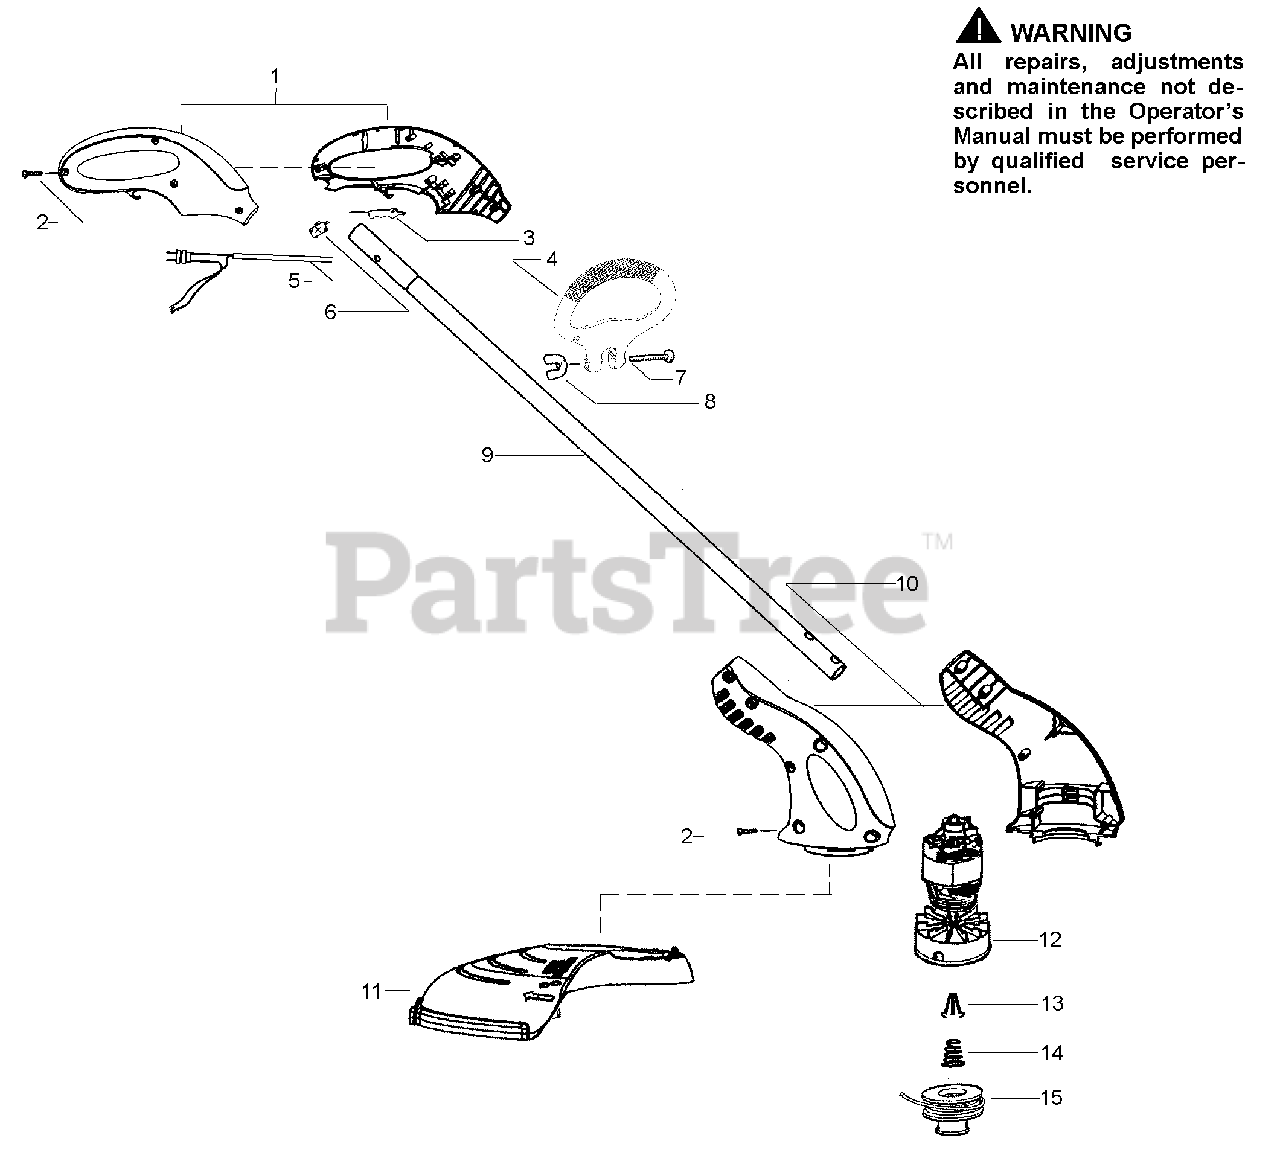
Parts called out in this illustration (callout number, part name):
1	Handle Set
4	Handle-Assist
5	Assy-Wiring Harness
8	Wingnut
9	Assy-Tube w/Decal
10	Housing Set
11	Assy-Shield
12	Assy-Motor/Hub
13	Retainer-Spool
14	Spring-Return
15	Accy-Spool w/Line
